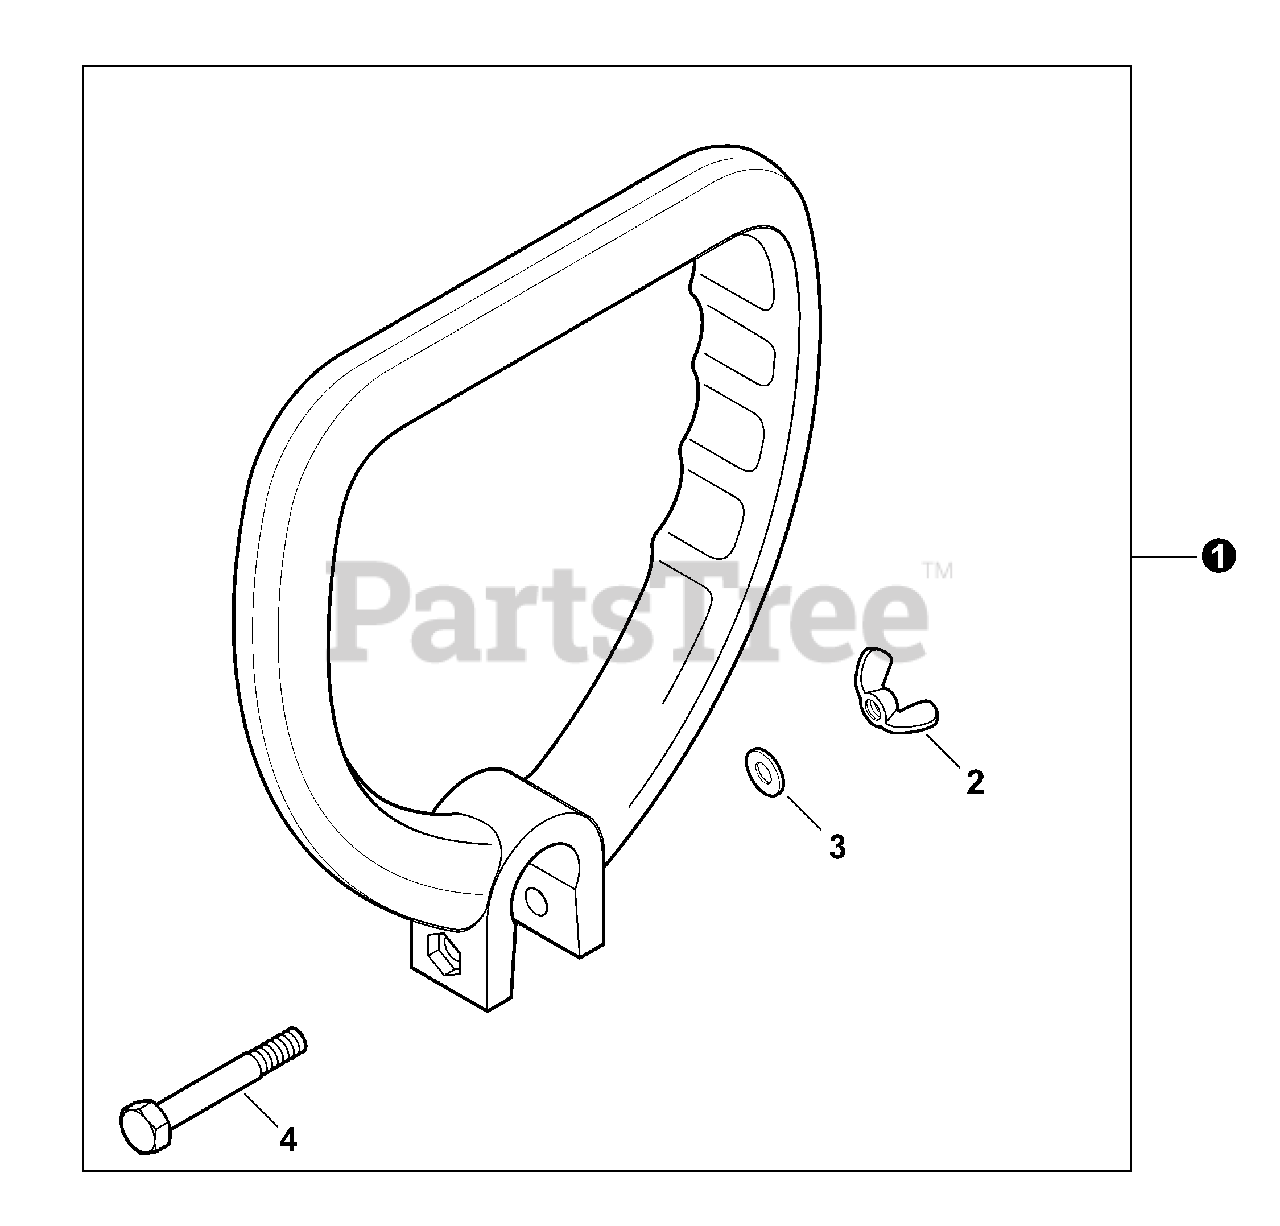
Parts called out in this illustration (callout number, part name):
1	FRONT HANDLE ASSY
2	WINGNUT - 1/4-20
3	WASHER - 1/4"
4	BOLT - 1/4-20 X 1-3/4"
